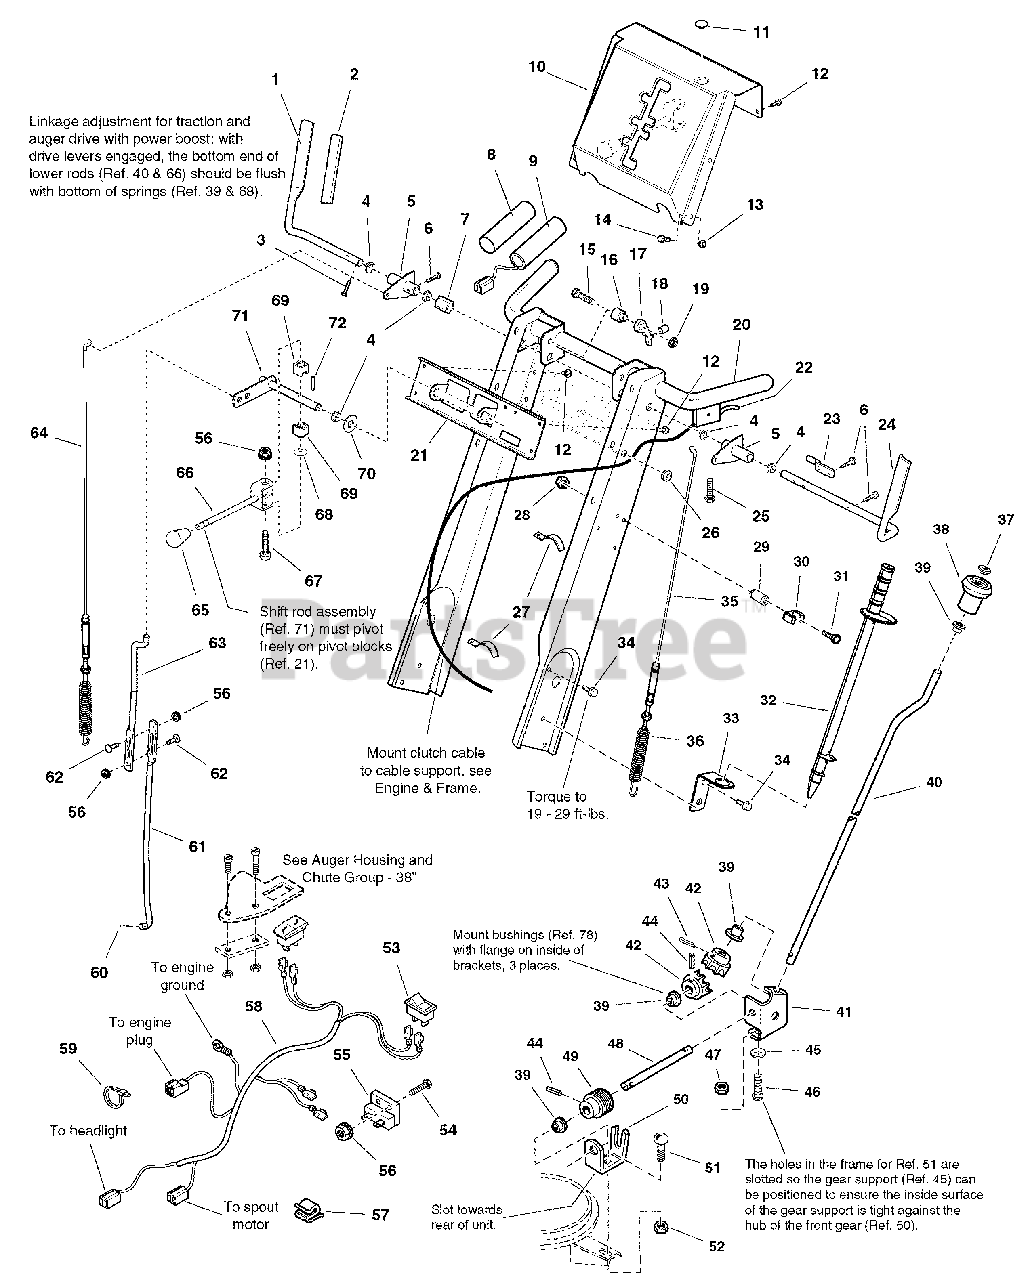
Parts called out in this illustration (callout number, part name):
1	HANDLE, Clutch R.H.
2	GRIP, Handle Clutch, Black
3	CAPSCREW, Hex Washer Head Taptite #10-24 x 1
4	BUSHING, 1/2 ID x 3/4 OD x 1/4, Plastic
5	LEVER & TUBE ASSEMBLY, Clutch
6	CAPSCREW, Hex Washer Head Taptite #12-24 x 1
7	GUIDE, Control
8	GRIP, Black Soft 1 in. (24 in. & 28 in. Models Only)
9	HAND GRIP, Heated 1 in. (32 & 38 in. Models Only)
11	PLUG, Button (38 in. Models Only)
12	CAPSCREW, Hex Washer Head Taptite 1/4-20 x 3/4
13	NUT, Hex Flange Whiz Lock 1/4-20
14	CAPSCREW, Hex Washer Head, 1/4-20 x 3/4 G5
15	CAPSCREW, Hex Flange Whiz Lock, 5/16-18 x 1-1/2
16	SPACER, 21/64 ID x 13/16 OD x 15/16
17	LATCH, Control
18	SPRING, Compression
19	NUT, Hex Flange 5/16-18 ESNA
20	HANDLE ASSEMBLY, Channel
21	BRACKET, Shift Control
22	CABLE & HANDLE ASSEMBLY, Clutch L.H.
23	ROD, Control 2 in. Flat
24	HANDLE, Clutch L.H.
25	SCREW, Pan Head Torx #10 x 1/2 Thick Cut
26	GROMMET, 1/2
27	CLIP, Wire
28	NUT, Hex Lock 10-24 with Nylon Insert NC3B (Quantity 3 used no 32 in. models)
29	SPACER, 17/64 ID x 3/8 OD x 21/64
30	CLIP, Clean Out Tool
31	SCREW, Phillips #10-24 x 3/4
32	TOOL, Clean Out
33	BRACKET, Clean Out Tool
34	CAPSCREW, Hex Serrated Flange Tap, 5/16-18 x 1
35	CABLE ASSEMBLY, LH (Includes Ref. No. 36)
36	SPRING, Extension 3-11/32 Long
37	NUT, Push Pal (Used on all models Except 38 in. Models)
38	KNOB, Spinner, Soft (Used on all modles Except 38 in. Models)
39	BUSHING, 3/8 ID x 7/16 OD x 13/64, Nylon (Used on all models Except 38 in. Models)
40	ROD, Chute Control, 27 in. Long (Used on all models Except 38 in. Models)
41	SUPPORT, Gear (Used on all models Except 38 in. Models)
42	GEAR, Powered Metal (Used on all models Except 38 in. Models)
43	PIN, Cotter 1/8 x 1 (Used on all models Except 38 in. Models)
44	PIN, Spring 1/8 x 3/4 (Used on all models Except 38 in. Models)
45	NUT, Push for 1/4 Diameter Thread
46	CARRIAGE BOLT, 1/4-20 x 5/8 G5 (Used on all models Except 38 in. Models)
47	NUT, Hex Flange Whiz Lock, 1/4-20 Small (Used on all models Except 38 in. Models)
48	ROD, Chute Worm, 18 Long (Used on all models Except 38 in. Models)
49	WORM, Chute, L.H. (Used on all models Except 38 in. Models)
50	SUPPORT, Worm (Used on all models Except 38 in. Models)
51	CARRIAGE BOLT, 5/16-18 x 3/4 G5 (Used on all models Except 38 in. Models)
52	NUT, Hex KEPS Conical Washer, 5/16-18 (Used on all models Except 38 in. Models)
53	SWITCH, Hand Warmer (32 & 38 in. Models Only)
54	CAPSCREW, Hex Head, 1/4-20 x 3/4 G5 (32 & 38 in. Models Only)
55	RESISTOR BLOCK, Male Terminal (32 & 38 in. Models Only)
56	NUT, Hex KEPS, 1/4-20 Conical Washer
57	CLIP, Wire (Spout Rotator Models Only)
58	HARNESS, Wiring (Handwarmer Models Only)
58	HARNESS, Wiring (Handwarmer & Spout Rotator Models Only)
59	TIE, Self Locking 7-5/16 (32 & 38 in. Models Only)
60	PIN, Quick
61	ROD, Lower Shift 15-21/64 Long
62	CARRIAGE BOLT, 1/4-20 x 3/4 G5
63	ROD, Upper Shift 11-3/8 Long
64	CABLE ASSEMBLY, RH
66	ROD & CLEVIS ASSEMBLY, Shift
67	CAPSCREW, Hex Flange Whiz Lock 1/4-20 x 2-1/4
68	WASHER, Curved
69	BLOCK, Pivot, Powdered Metal
70	WASHER, 1/2
71	ROD & ARM ASSEMBLY, Pivot
72	CLIP, Hair Pin
